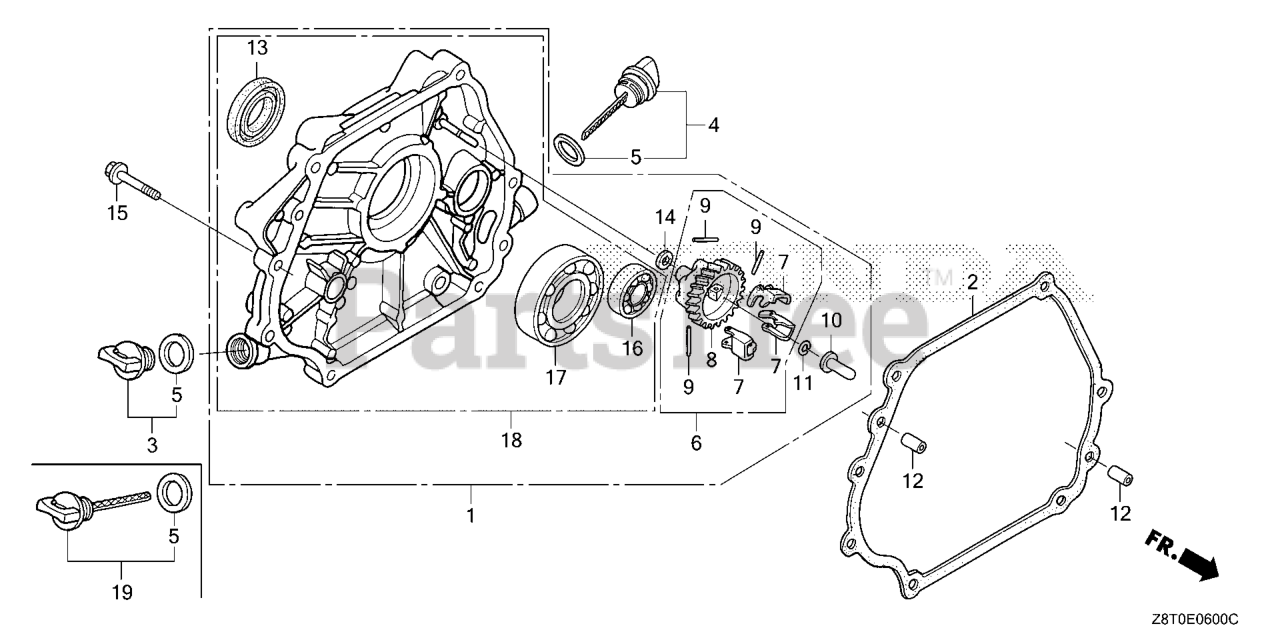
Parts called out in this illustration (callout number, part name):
1	COVER ASSY., CRANKCASE
2	GASKET, CRANKCASE COVER
3	CAP ASSY., OIL FILLER
4	CAP ASSY., OIL FILLER
5	GASKET, OIL FILLER CAP
6	GOVERNOR ASSY.
7	WEIGHT, GOVERNOR
8	HOLDER, GOVERNOR WEIGHT
9	PIN, GOVERNOR WEIGHT
10	SLIDER, GOVERNOR
11	CLIP, GOVERNOR HOLDER
12	PIN, DOWEL (8X12)
13	OIL SEAL (35X52X8) (NOK)
14	WASHER, PLAIN (6MM)
15	BOLT, FLANGE (8X40) Use up to Engine SN 1003236.
16	BEARING, RADIAL BALL (6202) (FUJIKOSHI)
16	BEARING, RADIAL BALL (6202)
17	BEARING, RADIAL BALL (6207)
